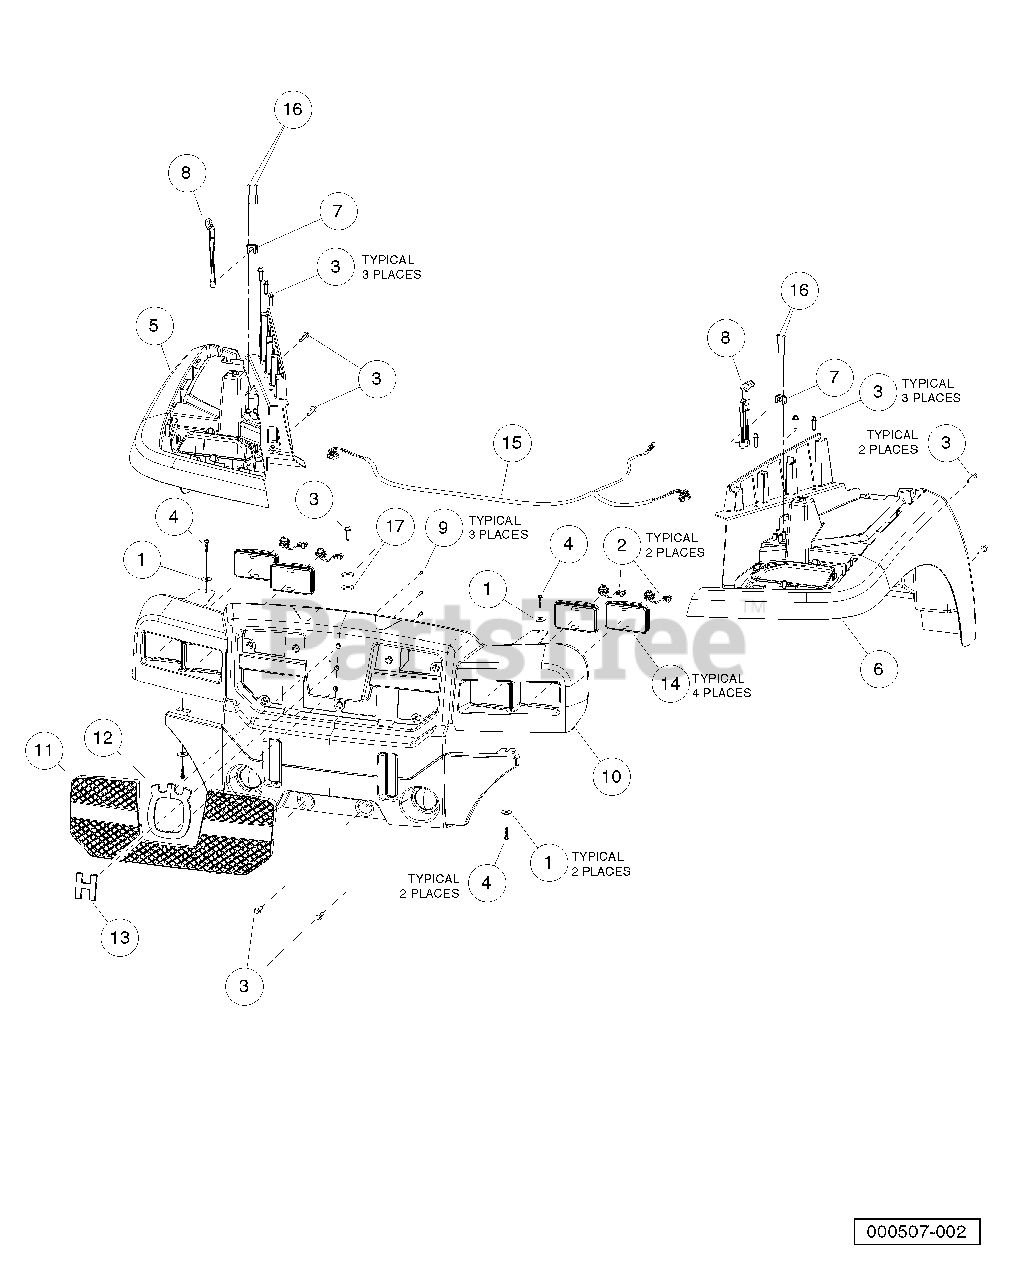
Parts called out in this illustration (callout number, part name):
1	Washer, 5/16 Type B Flat
2	Connector Harness Assembly, Headlight
3	Screw, M8X1.25X30, Hex
4	Screw,m6,torx,interlock,thread
5	Fender, Front, Pass, AWD
6	Fender, Front, Drv, AWD
7	Bracket, Latch, Draw
8	Latch, Draw, Hood
9	Screw, D50x16, Torx PN Hd PT
10	Fascia, Husqvarna
11	Grill, Husqvarna
12	Emblem, Husqvarna, Outer
13	Emblem, Husqvarna, Inner
14	Headlamp, 3x5 Rectangular
15	Harness, Bct/huv Restyle Headlight
16	Screw, #8x2.00 AB Thd, Hex Hd
17	Washer, 3/8 Type B Flat
